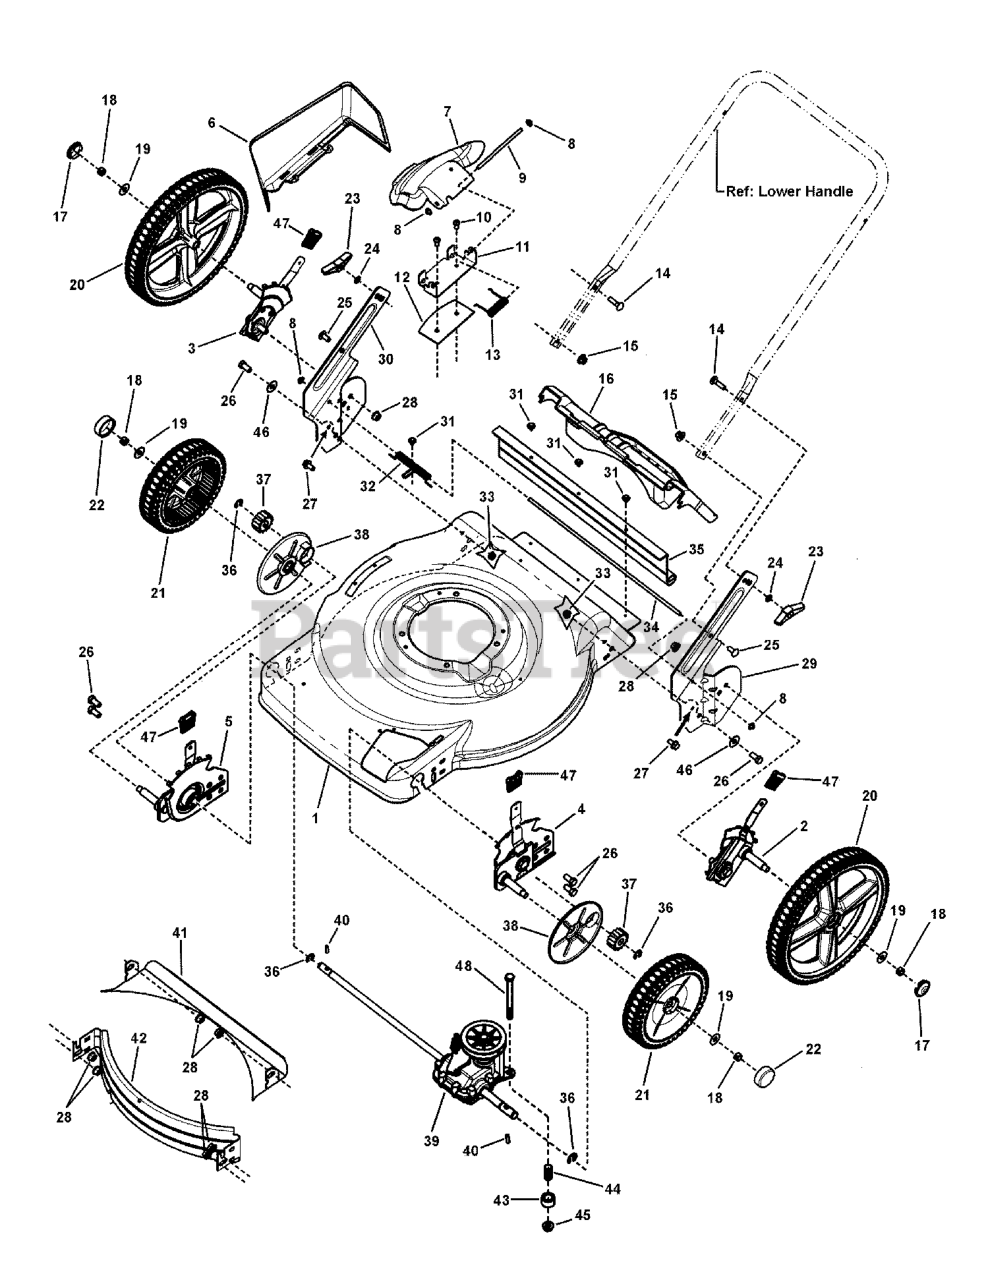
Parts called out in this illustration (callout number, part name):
1	DECK, 22 WALK, 3-N-1
2	ASSEMBLY, Height-Of-Cut, 22, 7 Position, Left Rear
3	ASSEMBLY, Height-Of-Cut, 22, 7 Position, Right Rear
4	ASSEMBLY, Height-Of-Cut, 22", Propelled, 7 Position, Left Front
5	ASSEMBLY, Height-Of-Cut, 22, Propelled, 7 Position, Right Front
6	SIDE CHUTE, Plastic, Black
7	COVER, Mulch, Plastic, Black
8	PUSHNUT, 1/4"
9	ROD, Chute Pivot (1/4" Dia. x 5.55")
10	SCREW, Torx,, 1/4-20 x 11/16
11	BRACKET, Chute
12	PLATE, Mulch
13	SPRING, Torsion, Chute
14	BOLT, Carriage, 5/16-18 x 1
15	NUT, Hex, 5/16-18
16	DOOR, Rear Discharge
17	HUBCAP, 12 Wheel
18	NUT, Centerlock, 3/8-16
19	WASHER, Flat, 3/8 ID x 1 OD
20	ASSY, Wheel, 12" x 2" Idle, NB, Murray Tread, Pewter
21	WHEEL, 8 x 2, Drive
23	WINGKNOB, 5/16-18
24	WASHER, Internal Tooth Lock, 5/16"
25	BOLT, Carriage, 5/16-18 x 3/4"
26	CAPSCREW, Hex Head, 3/8-16 x 3/4
27	BOLT, Hex Flange, 5/16-18 x 5/8
28	NUT, Hex Flange,, 3/8-16
29	BRACKET, Lower Handle, Left
30	BRACKET, Lower Handle, Right
31	SCREW, Self Tap, SEMS, 10-24 x 1/2
32	SPRING, Torsion, Rear Door
33	NUT, Hex Flange Lock, 5/16-18
34	ROD, Pivot, Rear Door
35	GUARD, Rear, 22 HW (19-1/2 long)
36	RETAINING RING
37	GEAR, Pinion
38	SHIELD, Dust
39	TRANSMISSION, 22" WBM Single Speed, Front Wheel Drive
40	PIN, Drive, 22 WBM, FWD
41	BAFFLE, Rear
42	BAFFLE, Front, 22 WBM
43	SPACER, Drive Transmission
44	SPRING, Compression
45	NUT, Hex Flange Centerlock, 5/16-18
46	WASHER, Flat, 3/8 x 7/8
47	GRIP, Height Latch
48	BOLT, Hex, 5/16-18 x 3
